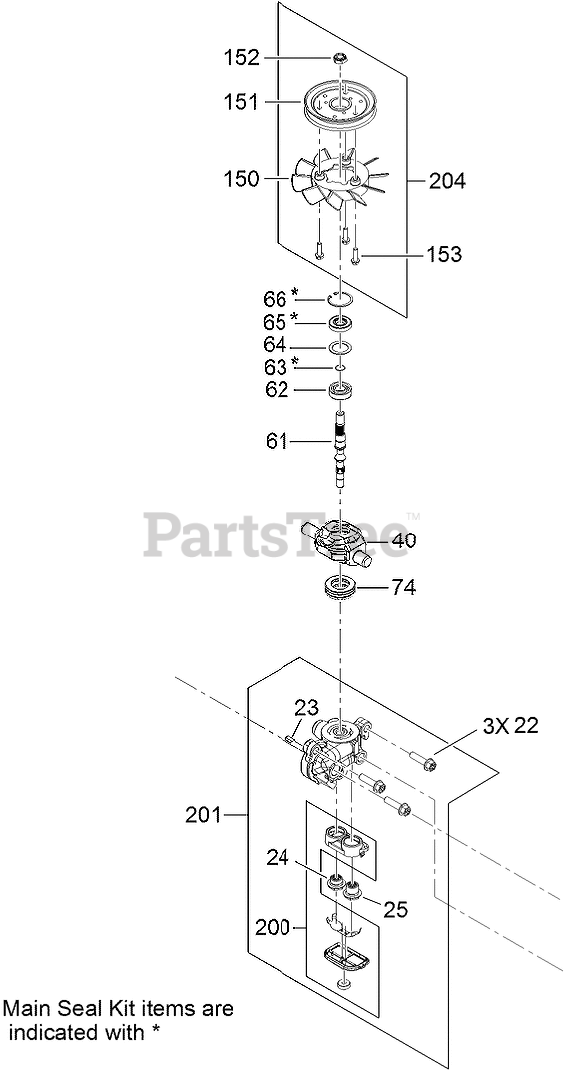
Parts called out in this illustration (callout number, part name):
22	SCREW-HFHC
23	PLATE-BYPASS
24	CHECK PLUG ASM
25	CHECK PLUG ASM
40	TRUNNION-PLATE, SWASH
61	SHAFT-INPUT
62	BEARING-BALL
63	RING-RETAINING, WIRE
64	SPACER
65	SEAL-LIP
66	RING-RETAINING
74	BEARING-THRUST, BALL
150	FAN
151	PULLEY ASM
152	NUT-HEX JAM
200	FILTER KIT
201	CENTER SECTION KIT
204	FAN PULLEY KIT
